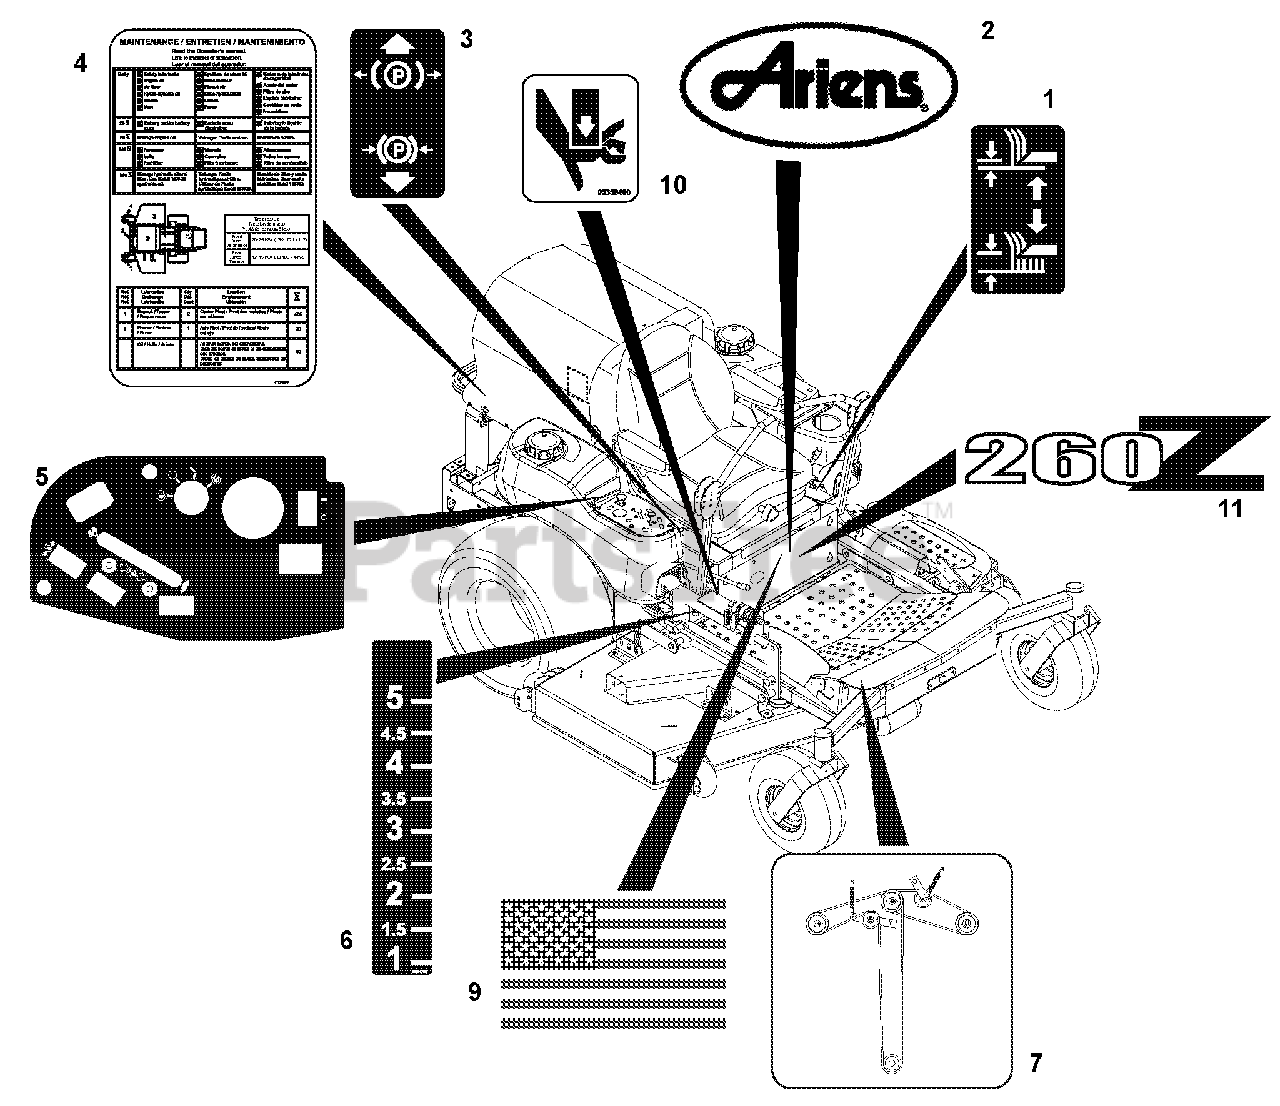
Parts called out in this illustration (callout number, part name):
1	DECAL- LIFT LEVER
2	DECAL, ARIENS
3	DECAL, PARKING BRAKE LEVER
4	DECAL- SERVICE INSTRUCTIONS
5	DECAL, CONTROL PANEL L/C - GAS
6	DECAL, HEIGHT OF CUT
7	DECAL, GRAVELY BELT DIAGRAM
8	DECAL, PM-260Z
9	DECAL, AMERICAN FLAG
10	DECAL, PINCH POINT
11	DECAL, PM-260Z
